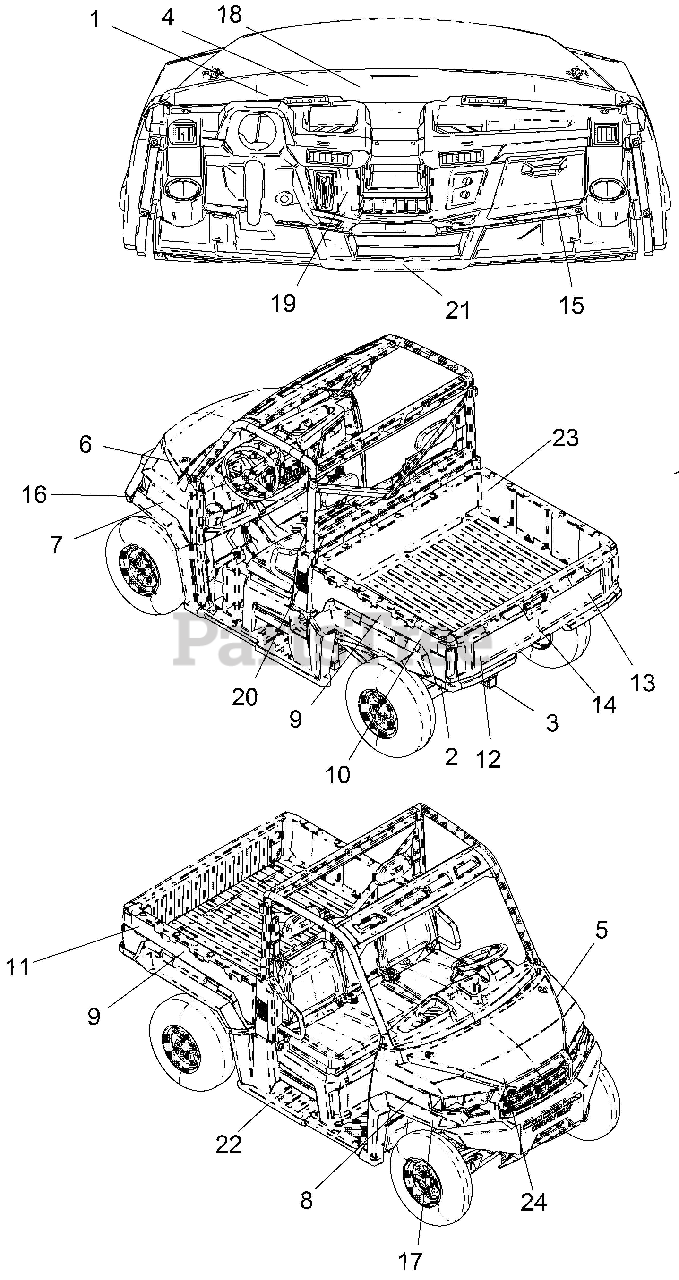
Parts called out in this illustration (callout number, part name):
1	DECAL, AGE WARNING 16
2	DECAL, REFLECTOR RED
3	DECAL, WARNING TRAILER LOAD
4	LABEL, OPEI COMPLIANCE
5	DECAL, HOOD TOP EFI LH
6	DECAL, HOOD TOP EFI RH
7	DECAL, HOOD SIDE ATLAS LH
8	DECAL, HOOD SIDE ATLAS RH
9	DECAL, BOX SIDE GRAVELY
10	DECAL, BOX SIDE JSV 3000 LH
11	DECAL, BOX SIDE JSV 3000 RH
12	DECAL, TAILGATE ATLAS LH
13	DECAL, TAILGATE AWD RH
14	DECAL, TAILGATE GRAVELY CENTER
15	DECAL, GLOVEBOX COVER
16	DECAL, REFLECTOR AMBER LH
17	DECAL, REFLECTOR AMBER RH
18	DECAL, WARNING DISC GRAVELY
19	DECAL, CAUTION SHIFT/BRAKE
20	DECAL, ROPS GRAVELY 3000
21	DECAL,WARNING PASS/TIRE PRESS
22	DECAL NOT A STEP
23	DECAL-WARN,FUEL TRANSPORT
24	DECAL-COOLANT
